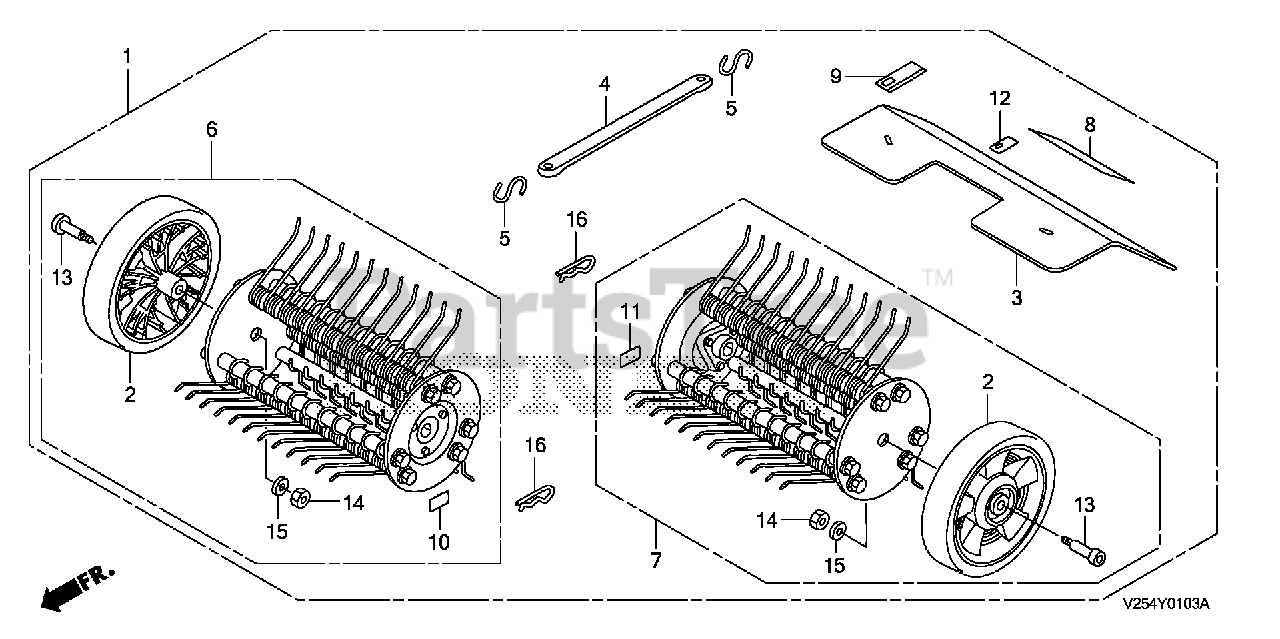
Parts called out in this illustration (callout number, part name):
1	DE-THATCHER KIT (USA) (NOT AVAILABLE)
2	WHEEL, RR.
3	FENDER, DE-THATCHER (NOT AVAILABLE)
4	STRAP, FENDER
5	HOOK, S (NOT AVAILABLE)
6	DE-THATCHER, R. (NOT AVAILABLE)
7	DE-THATCHER, L. (NOT AVAILABLE)
8	LABEL, TINE DANGER (ENGLISH)
9	MARK, OIL LEVEL CHECK (ENGLISH)
10	DECAL, R. (NOT AVAILABLE)
11	DECAL, L. (NOT AVAILABLE)
12	MARK, DE-THATCHER NOTICE (ENGLISH)
13	BOLT, SHOULDER (3/8")
14	NUT (3/8")
15	WASHER, LOCK (3/8")
16	PIN, LOCK (17MM)
